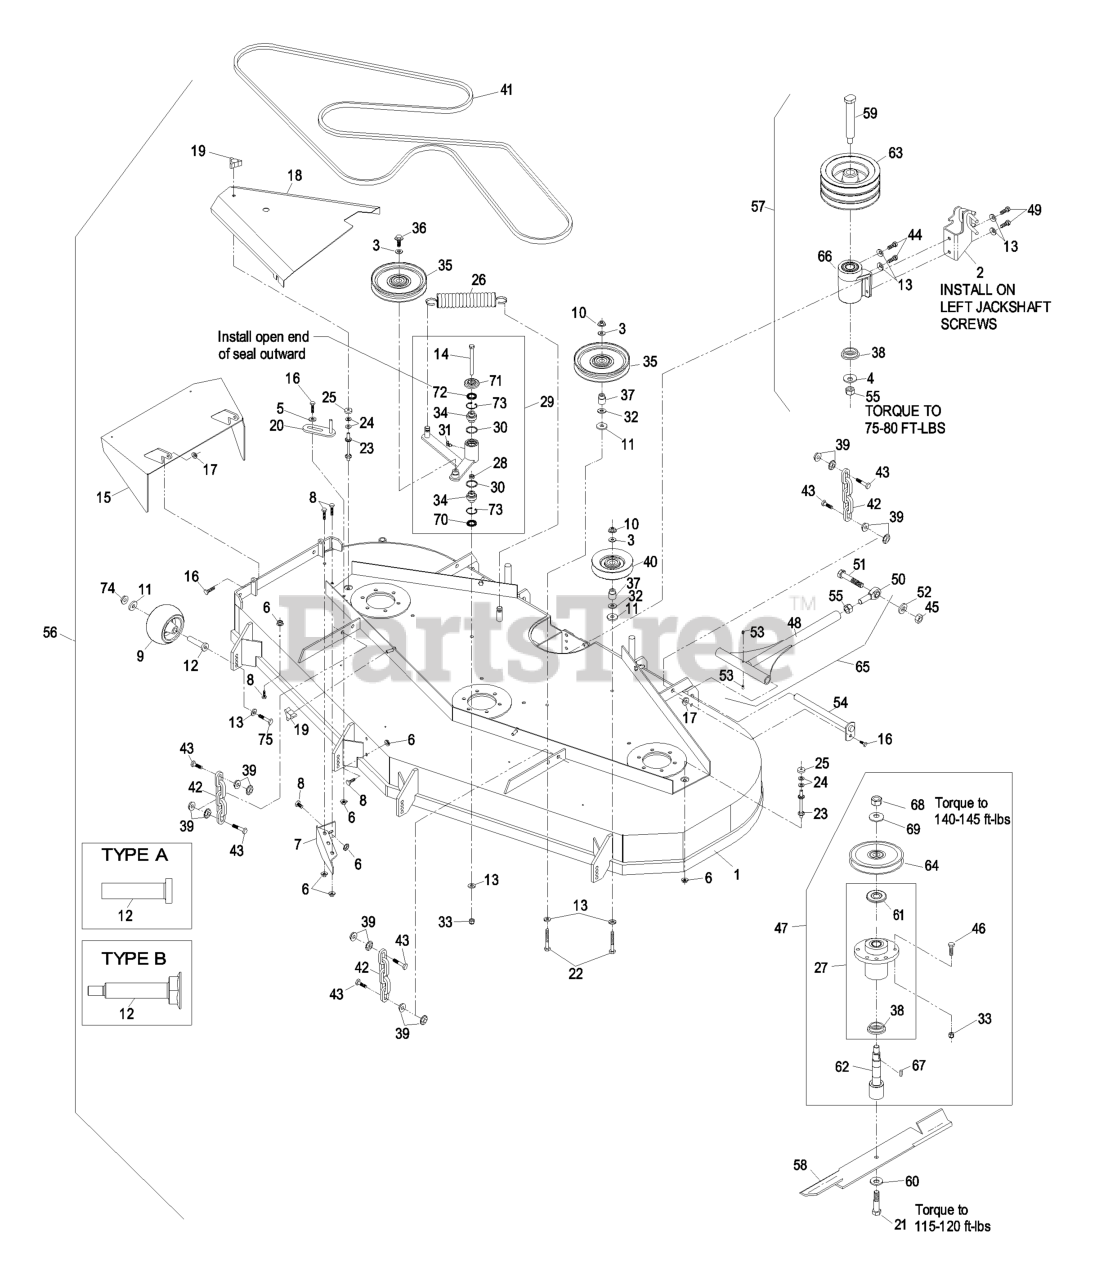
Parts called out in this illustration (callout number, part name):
1	ASM,DECK W/DECALS LZ/XP72
3	WASHER-FLAT
4	WASHER-SPRING
5	WASHER-SPRING
7	WLD,BAFFLE DISCHARGE
8	SCREW-HH
9	ROLLER-SCALP, ANTI
10	NUT-HHF, WHIZ
12	BUSHING-ROLLER
13	WASHER-BELLEVILLE
14	SCREW-HH
15	WLD,CHUTE 72
16	SCREW-HH
17	NUT-LOCK, NI
18	SHIELD,BELT RH
19	KNOB-3 PRONG
20	GUIDE-BELT
21	SCREW-CAP
22	SCREW-HH
23	STUD-SHIELD, BELT (SHORT)
24	WASHER-FLAT
27	KIT, CUTTER HOUSING
29	KIT,DECK IDLER LZ/XP
31	FITTING-GREASE, 90 DEG
32	WASHER-FLAT
33	NUT-LOCK, NI
34	BEARING-SPHERICAL
36	SCREW-HHF
37	BUSHING-IDLER
38	SPACER-GUARD, BOTTOM
40	PULLEY-IDLER
41	BELT-V
42	CHAIN-LIFT, DECK
43	SCREW-HH
44	SCREW-HH
45	NUT-HEX
46	SCREW-HH
47	ASM, CUTTER HSG COPL 72
49	SCREW-HH
50	BALLJOINT-SPHERICAL
51	SCREW-HH
52	WASHER-LOCK
53	FITTING-GREASE
54	PIN-STRUT
55	NUT-HEX
56	Complete Deck Assy
57	ASM,JACKSHAFT
59	JACKSHAFT
60	WASHER-BLADE BOLT, HEAVY
61	GUARD-BEARING, TOP
62	SPINDLE,SHORT
63	SHEAVE-JACKSHAFT
64	SHEAVE,BLADE DRIVE 7.5
65	STRUT WLDMT S/A
68	NUT-HH
70	SEAL-LIP, DOUBLE
71	GUARD-TOP
72	SEAL-LIP, SINGLE
73	RING-SNAP
74	NUT-HHF, WHIZ
75	SCREW-HH
